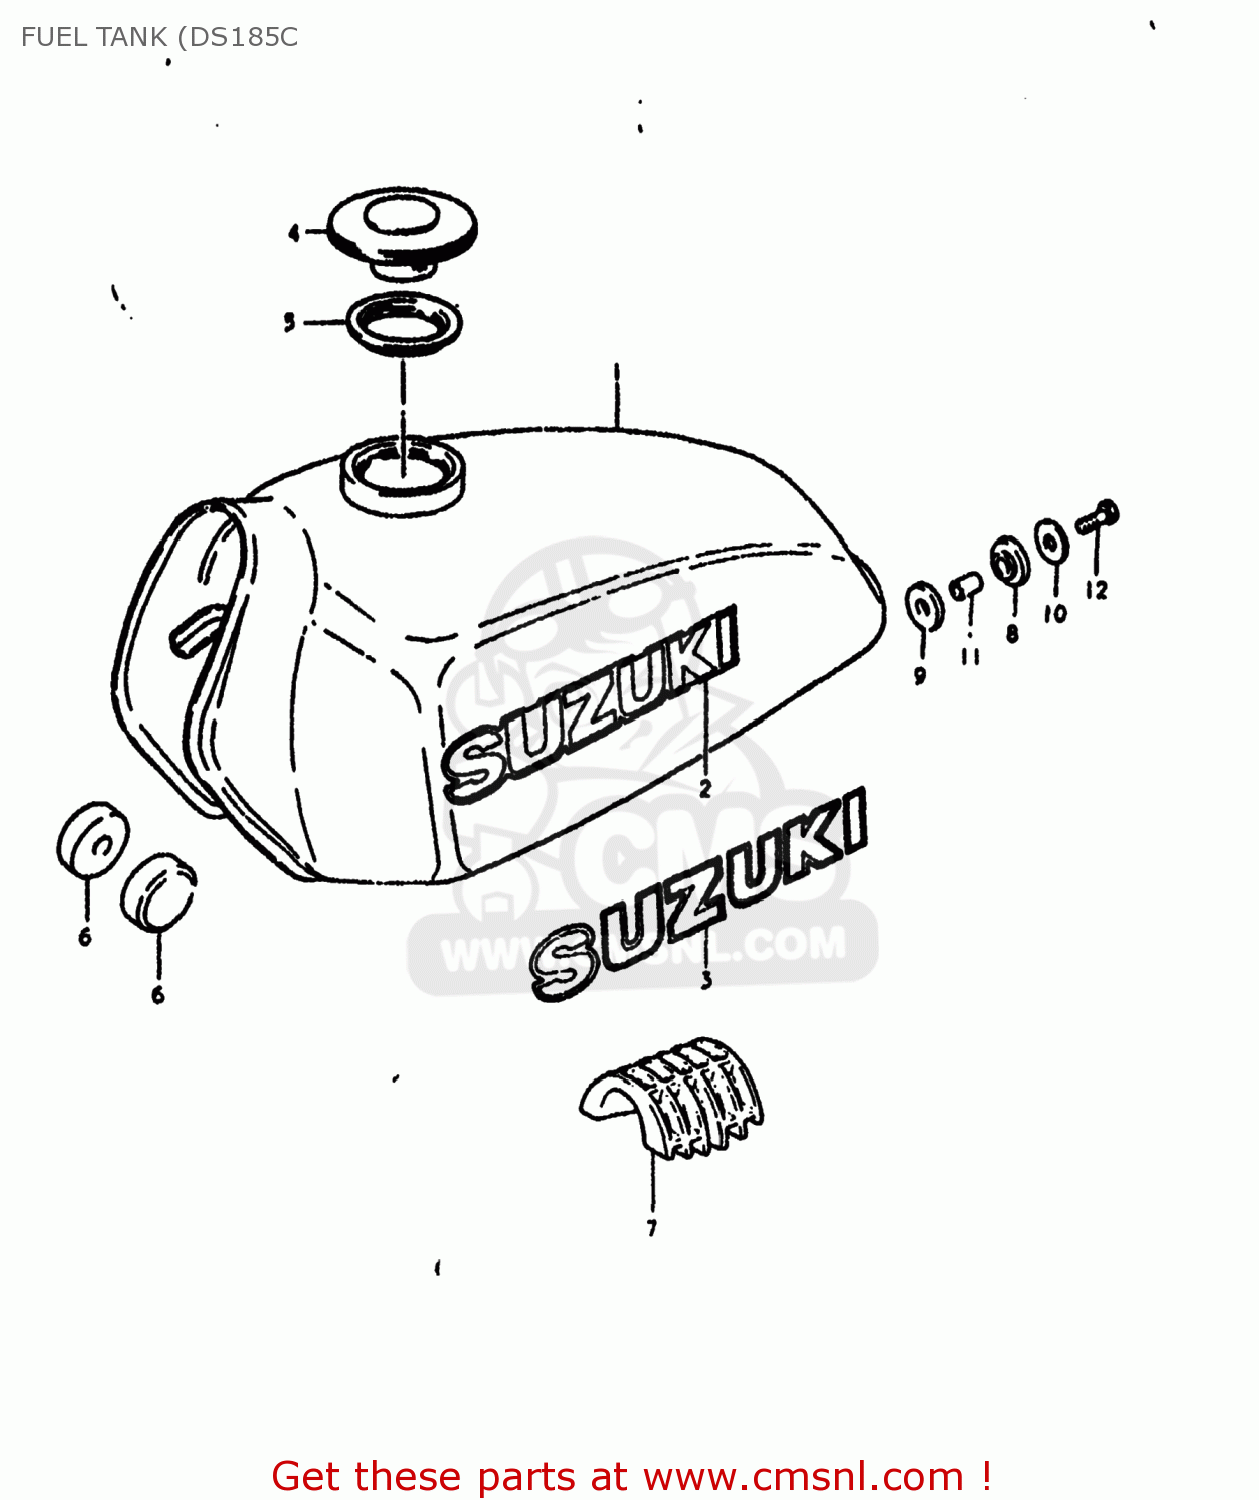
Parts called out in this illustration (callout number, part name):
1	TANK ASSEMBLY,FUEL
2	EMBLEM
3	EMBLEM
4	CAP,FUEL TANK
5	GASKET (NAS)
6	CUSHION
7	CUSHION
8	CUSHION
9	CUSHION
10	WASHER (8.5X29X1.6)
11	SPACER(8.1X11X5.4)
12	BOLT (8X30)
